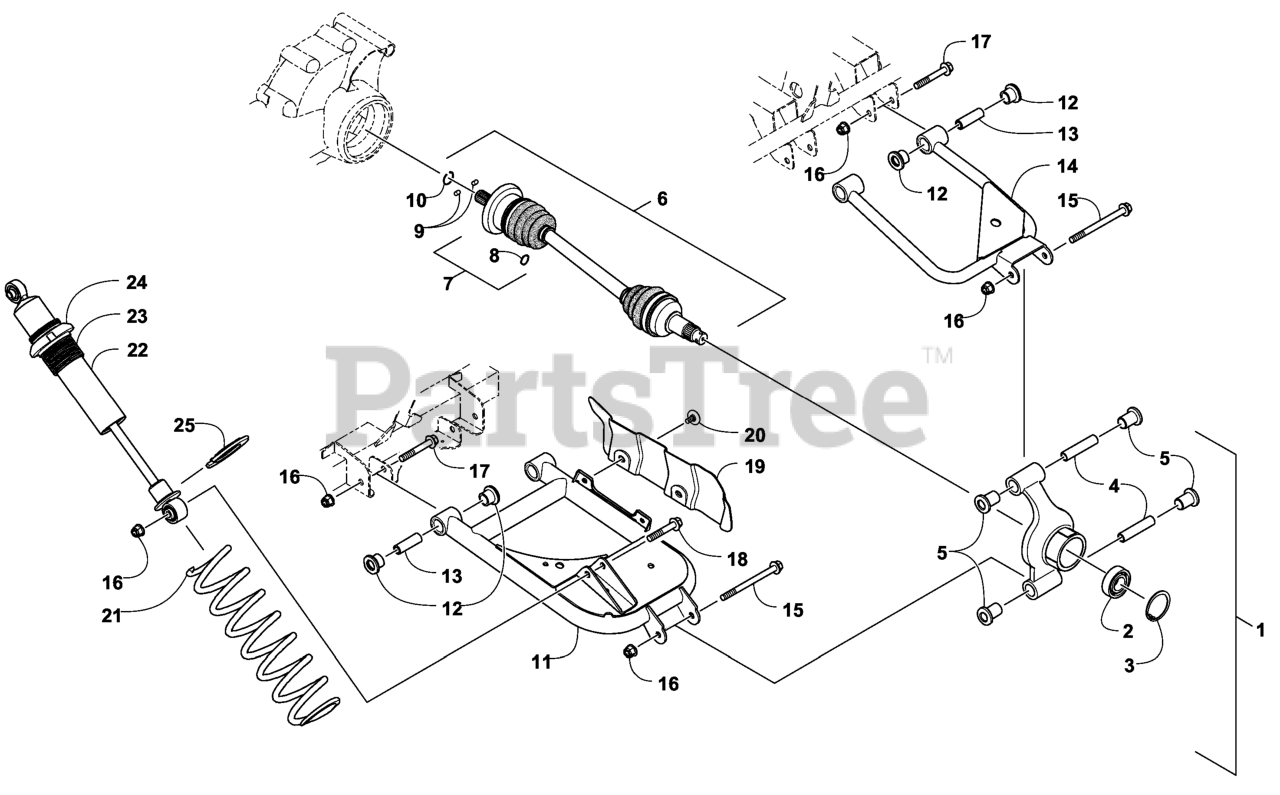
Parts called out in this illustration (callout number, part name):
1	KNUCKLE-REAR ASM
2	BEARING-WHEEL
3	RING-RETAINING
4	COLLAR-SUSPENSION BUSHING
5	BUSHING-SUSPENSION, REAR
6	AXLE-DRIVE, REAR
7	KIT-CV BOOT, UNIVERSAL
8	CIRCLI-HALFSHAFT, INTERNA
9	PIN-TRANSFER, LONG
10	CIRCLIP
11	A-ARM, REAR LOWER (RH ASM
11	A-ARM, REAR LOWER (LH ASM
12	BUSHING-SUSPENSION, A-ARM
13	COLLAR-SUSPENSION BUSHING
14	A-ARM, REAR UPPER (RH ASM
14	A-ARM, REAR UPPER (LH ASM
17	SCREW-HFH
18	SPRING-EXTENSION
19	GUARD-BOOT, REAR (RH)
19	GUARD-BOOT, REAR (LH)
20	SCREW-SELF TAP
21	SPRING-COIL, REAR
22	REAR SHOCK ABSORBER ASM
23	TUBE-RETAINER, THREADED
24	NUT-RETAINER
25	RETAINER-SPRING
